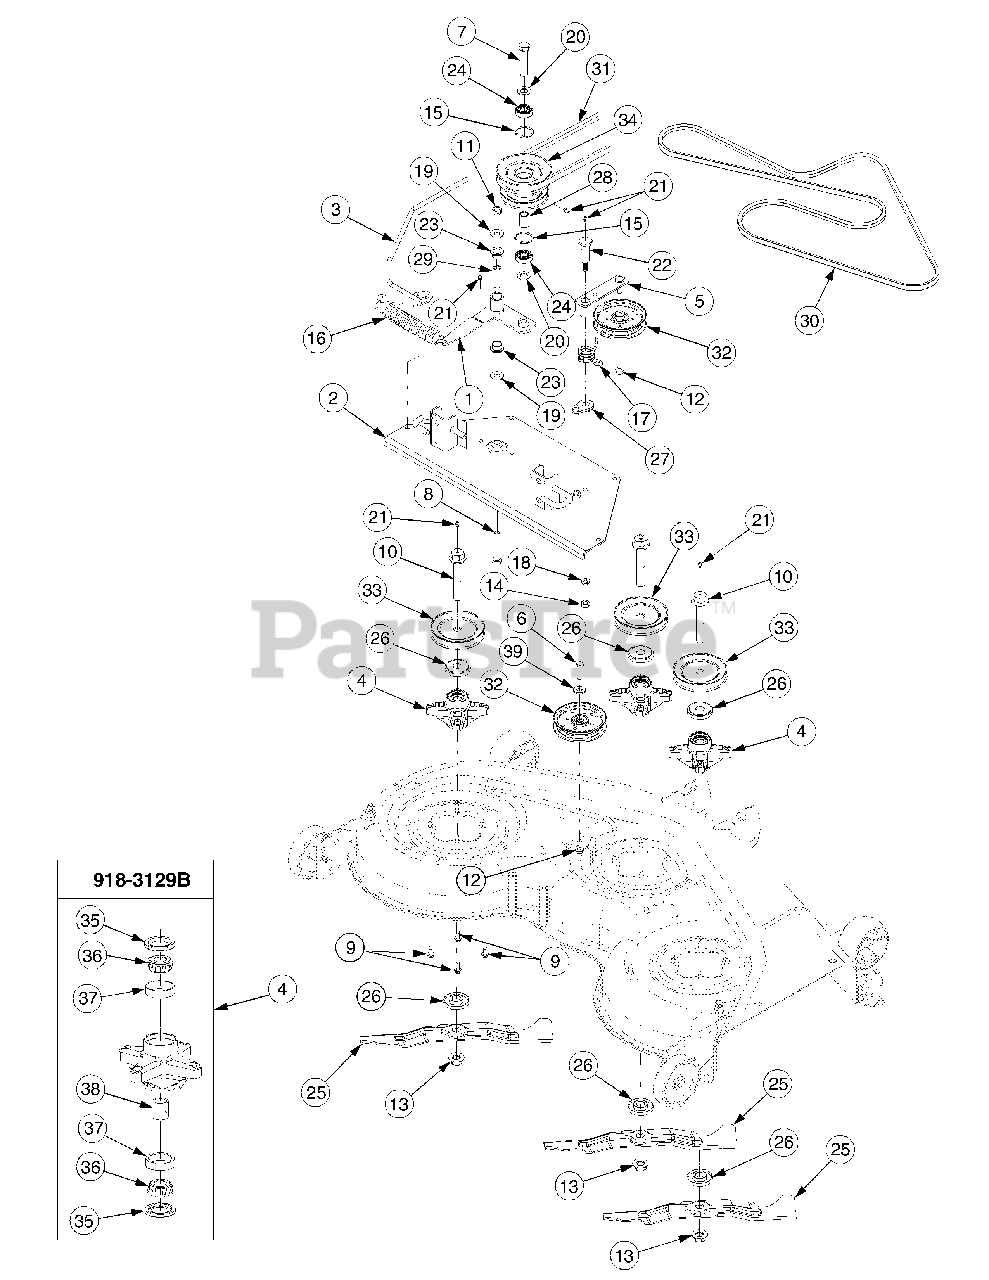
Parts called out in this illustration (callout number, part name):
1	Arm, Idler
4	Spindle Assembly
5	Arm, Idler
6	Screw, Hex Cap, 3/8-16 x 1.5 GR5
7	Screw, Hex Cap, 5/8-18 x 3 GR5
8	Screw, Hex Cap, 1/2-20 x 3 GR8
9	Screw, Hex Wash. Hd. Tapp 5/16-18 x .75
10	Bolt, Spindle, 3/4-16 x 4.25
11	Nut, Hex Center Lock, 1/2-20
12	Nut, Hex Flanged Lock, 3/8-16
13	Nut, Hex Flange, 3/4-16
14	Nut, Hex, 7/16-14 GR2
15	Snap Ring, Internal
16	Spring, Extension, 1.25 OD x 8.15
17	Spring, Torsion
18	Washer, Lock, 7/16
19	Washer, Flat, .5 x 1.25 x .1
20	Washer, Flat, .65 x 1.25 x .075
21	Fitting, 3/16 Drive Lube
22	Bolt, Shoulder, .68 x 2.11:7/ 16-14
23	Bearing, Flange
24	Bearing, Ball, .62 x 1.57 x .470
25	Blade, 2 in 1, 17.9"
26	Spacer, Deck Spindle
27	Retainer, Spring
28	Spacer, Pulley, .635 ID x .88 OD x
29	Spacer, Idlr Brkt, .51 ID x .75 OD x
30	Belt, Spindle, A-Section x 114.13"
31	Belt, PTO, B-Section x 111.4"
32	Pulley, Flat Idler, 4.25 OD
34	Pulley, Double
35	Seal, Oil, 1.25 x 1.874 x .25
36	Bearing, Cone
37	Cup, Bearing
38	Spacer, Bearing
39	Washer, Flat, .406 x .812 x .051
